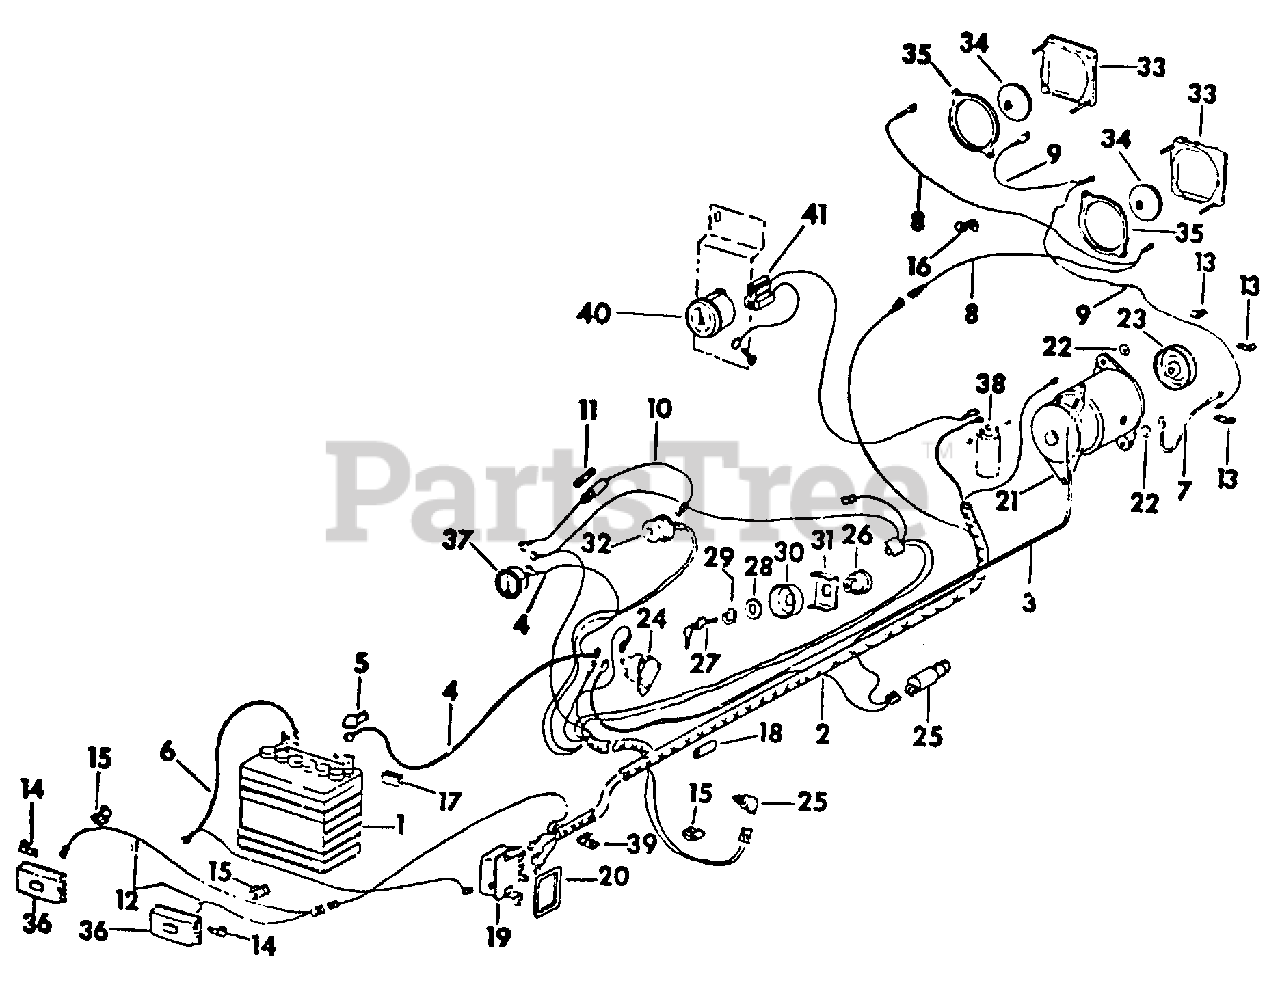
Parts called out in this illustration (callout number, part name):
1	Battery, IH Low Maintenance, 12 Volt
2	Cable Harness Rework Package
3	Cable, Magneto Switch to Generator A Terminal
4	Cable, Battery (Positive)
5	Cover, Battery Terminal
6	Cable, Battery Neg Terminal to Ground
7	Cable, Engine to Ground
8	Cable, Headlight
9	Cable, Headlight to Ground
10	Cable, Switch to Charge Indicator
11	Fuse, 10 Amp Slo-Blo
12	Cable, Taillight
13	Clip, Cable
14	Clip, Taillight
15	Clip, Safety Starting Switch Cable
17	Grommet, Seat Support Edge
18	Grommet, Frame Edge
19	Regulator, Voltage
20	Gasket, Voltage Regulator
21	Starter Generator Assy
22	Shim, Starter-Generator Mtg Bolt
23	Pulley, Starter-Generator Drive
24	Switch, Magnetic
25	Switch Assy, Neutral Starting
26	Switch w/Keys, Battery Ignition Key Start
27	Key, Ignition Switch
28	Washer, Battery Ignition Switch
29	Nut, Battery Ignition Switch
30	Socket, Ignition Switch
31	Retainer, Ignition Switch
32	Switch, Lighting
33	Rim, Headlight
34	Unit, Sealed Beam
35	Ring, Headlight Clamp
36	Taillight Assy
37	Indicator, Charge
38	Coil
39	Clip, Right Front Fender Mtg Screw Cable
40	Timer, Maintenance Minder
41	Cable, Maintenance Minder
